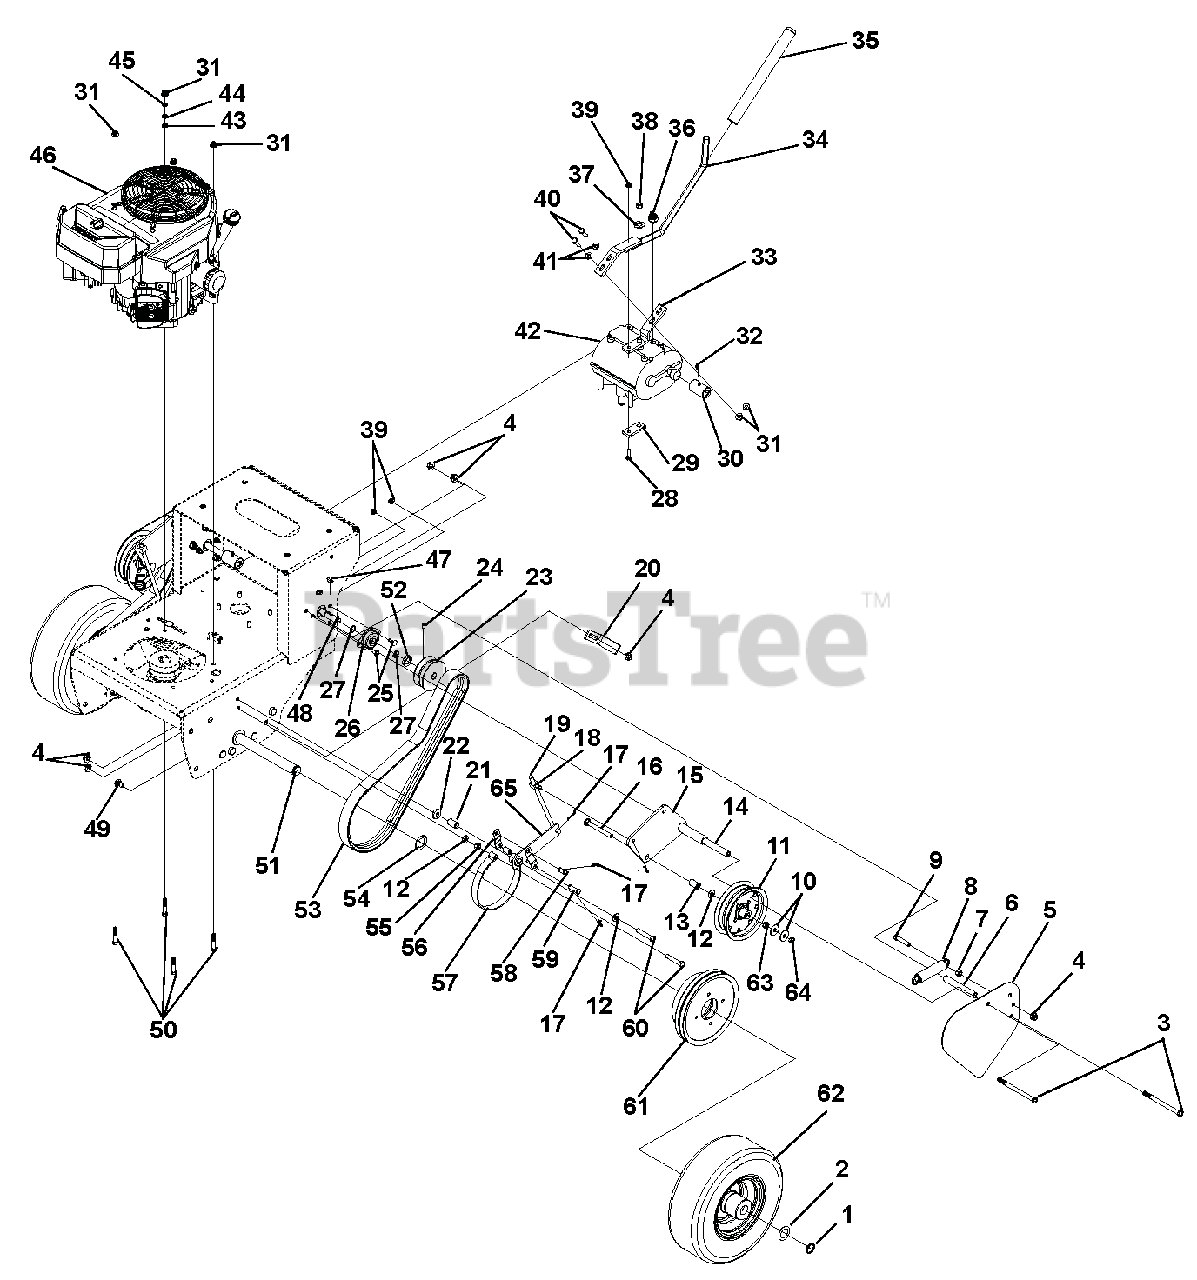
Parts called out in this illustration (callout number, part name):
1	RG-RTNG-EXT 1.00X.078
2	WSHR-FL-STL 1.010X1.505X.062YZ
3	BOLT, 3/8-16X5.00 HEX 5 Y
4	@NUT-LK-NYL-FLG .38-16 YWZC
5	COVER, TRACTION BELT
6	BUSH.,S.385X.610X4.32 ST
7	NUT, 3/8-16 STD HEX GR5 Y
8	SG-TENS .105X1.00X5.0
9	BOLT, 3/8-16X1.75 HEX 5 Y
10	WSHR-FL-STL .375X1.125X.065YWZ
11	PULLEY, FLAT 5.00X.375 W/BRG
12	WASHER, .406X.813X.065 FLAT Y
13	BSHG-SLV .375X.625X.1.000
14	BUSH.,S.385X.610X4.32 ST
15	WMT - WHEEL CLUTCHING ARM -LH
16	@BLT-RDHDSQNK .38-16X3.50 G5YZ
17	PIN-HAIR, ENDRIES #25 YWZC
18	SWIVEL, 3/8-24
19	ROD, BRAKE ACTUATING
20	PLATE, BENT BELT FINGER
21	BUSH.,S.391X.622X.950 ST
22	WSHR-FL-STL .406X1.00X.188 YWZ
23	SHEAVE-DRIVE 3.25 OD X .625 ID
24	SCR-SET .31-18X.38 SKHCUPDL
25	BOLT, 1/4-20X.750 CRG 5 Y
26	BRG-FLG .625X1.875X.797
27	RG-RTNG-EXT .579X.035
28	BOLT, 1/4-20X1.00 HEX 5 Y
29	PLATE, SHIFT
31	@NUT-LK-NYL-FLG .31-18 YWZC
32	FTG, 1/4-28 STRGT GREASE ZERK
33	BRACKET, SHIFT LEVER
34	WMT, SHIFT LEVER
35	GRIP, HANDLEBAR
36	SWITCH-NEUTRAL START N.O.
37	WSHR-LK .375X.130 YWZC
38	NUT-LK-CTR .375-24 YWZC
39	@NUT-LK-NYL-FLG .25-20 YWZC
40	BOLT, 5/16-18X3.25 HEX 5 Y
41	@WSHR-FL-STL.344X.688X.065YWZC
42	TRANSMISSION
43	WASHER, .313 MED SPRG LOCK Y
44	@NUT-LK-CTR-JAM .31-18 YWZC
45	@WSHR-LK-EXT.326X.599X.031YWZC
46	ENGINE, KAWI FH381V KAI 13HP
47	KEY-WDRF .19X.75 HRD #9
48	SHAFT, HALF
49	BOLT, 3/8-16X.750 CRG 5 LN Y
50	BOLT, 5/16-18X1.75 HEX 5 Y
51	SHAFT, AXLE
52	WSH, FLT .765"X.1.125"X.187"
53	BELT, GEAR DRIVE 49" EL COG
54	WSHR-HRD-THRS 1.007X1.542X.062
55	NUT, 3/8-16 STD HEX GR5 Y
56	LINK,BRAKE ARM
57	ASM, BRAKE BAND, PRO
58	PIN, CVS .375X.750X.516 Y
59	PIN-CLEV .38X1.25 YWZC
60	BOLT, 3/8-16X2.00 HEX 5 Y
61	ASSY, PULLEY & DRUM
62	ASSY, WHEEL AND TIRE 6X3.5
63	LOCKNUT, 3/8-16 CENTER Y
64	@NUT-LK-CTR-JAM .375-16 YWZC
65	WMT, BRAKE ACTUATING LEVER
